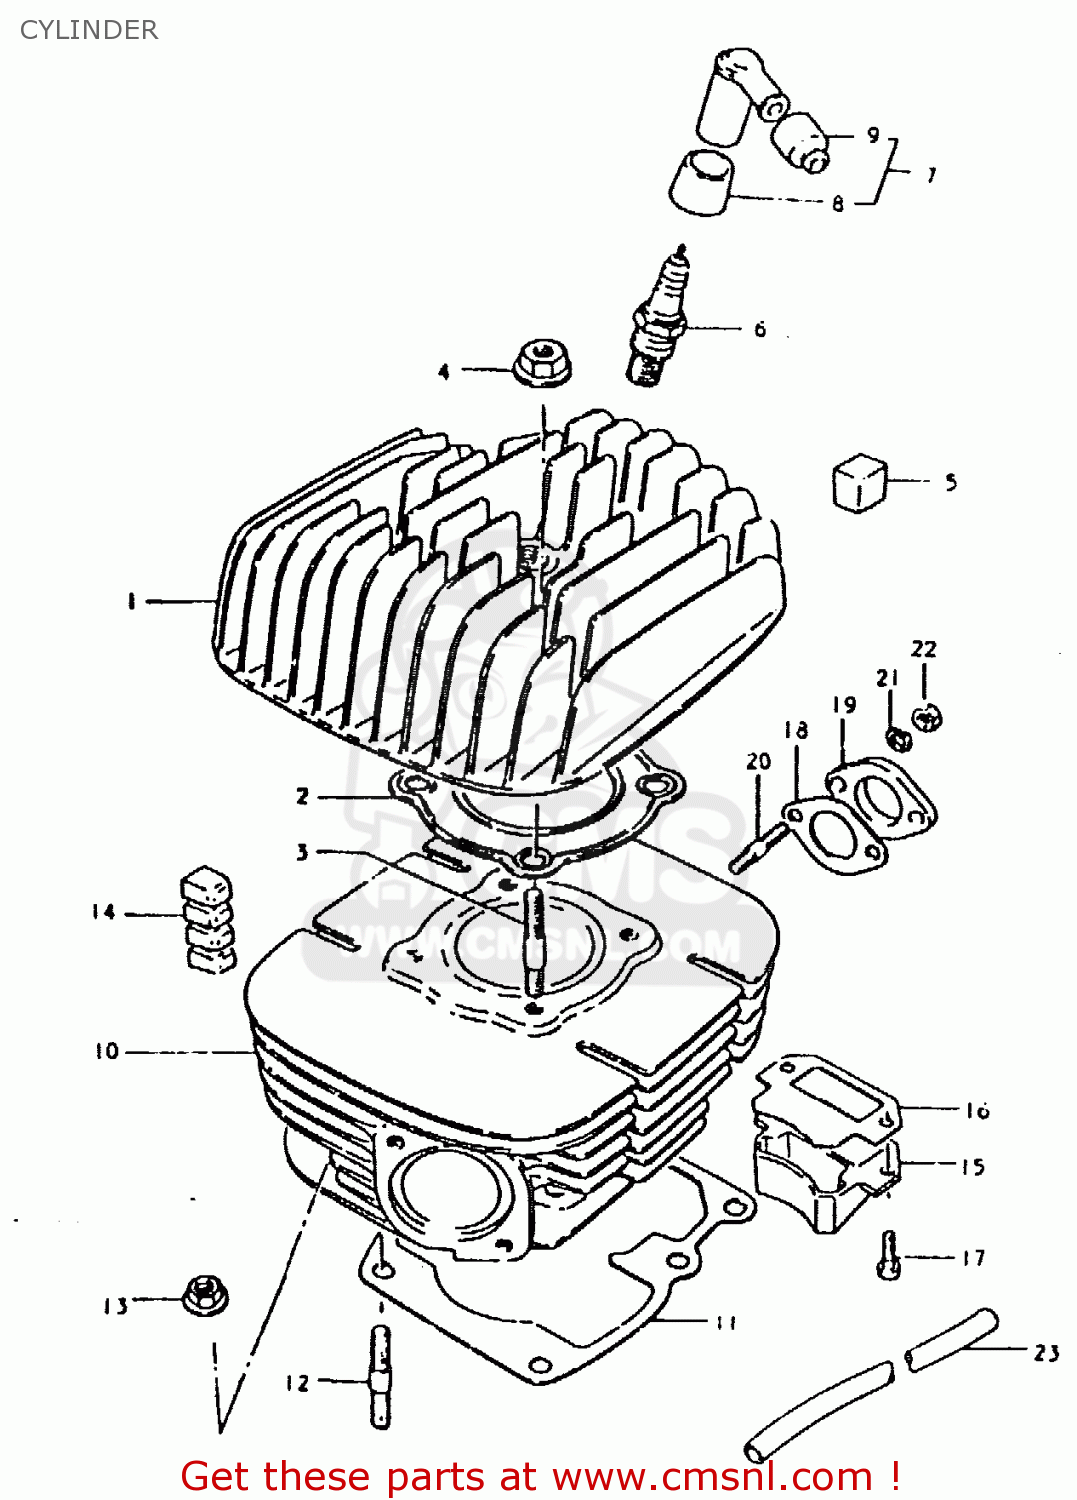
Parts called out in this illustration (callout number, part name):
1	HEAD,CYLINDER
2	GASKET,CYLINDER HEAD (MCA)
3	STUD BOLT
4	NUT
5	PAD,CYLINDER
6	SPARK PLUG BP8ES
7	CAP,SPARK PLUG
8	SEAL,SPARK PLUG
9	SEAL,SPARK PLU
10	CYLINDER
11	GASKET,CYLINDER (MCA)
12	STUD 8X25
13	NUT
14	PAD,CYLINDER
15	VALVE ASSEMBLY,REED
16	GASKET,REED VALVE (MCA)
17	SCREW
18	GASKET,CARBURETOR (MCA)
19	INSULATOR,CARBURETOR
20	STUD BOLT
21	LOCK WASHER
22	NUT
23	HOSE
